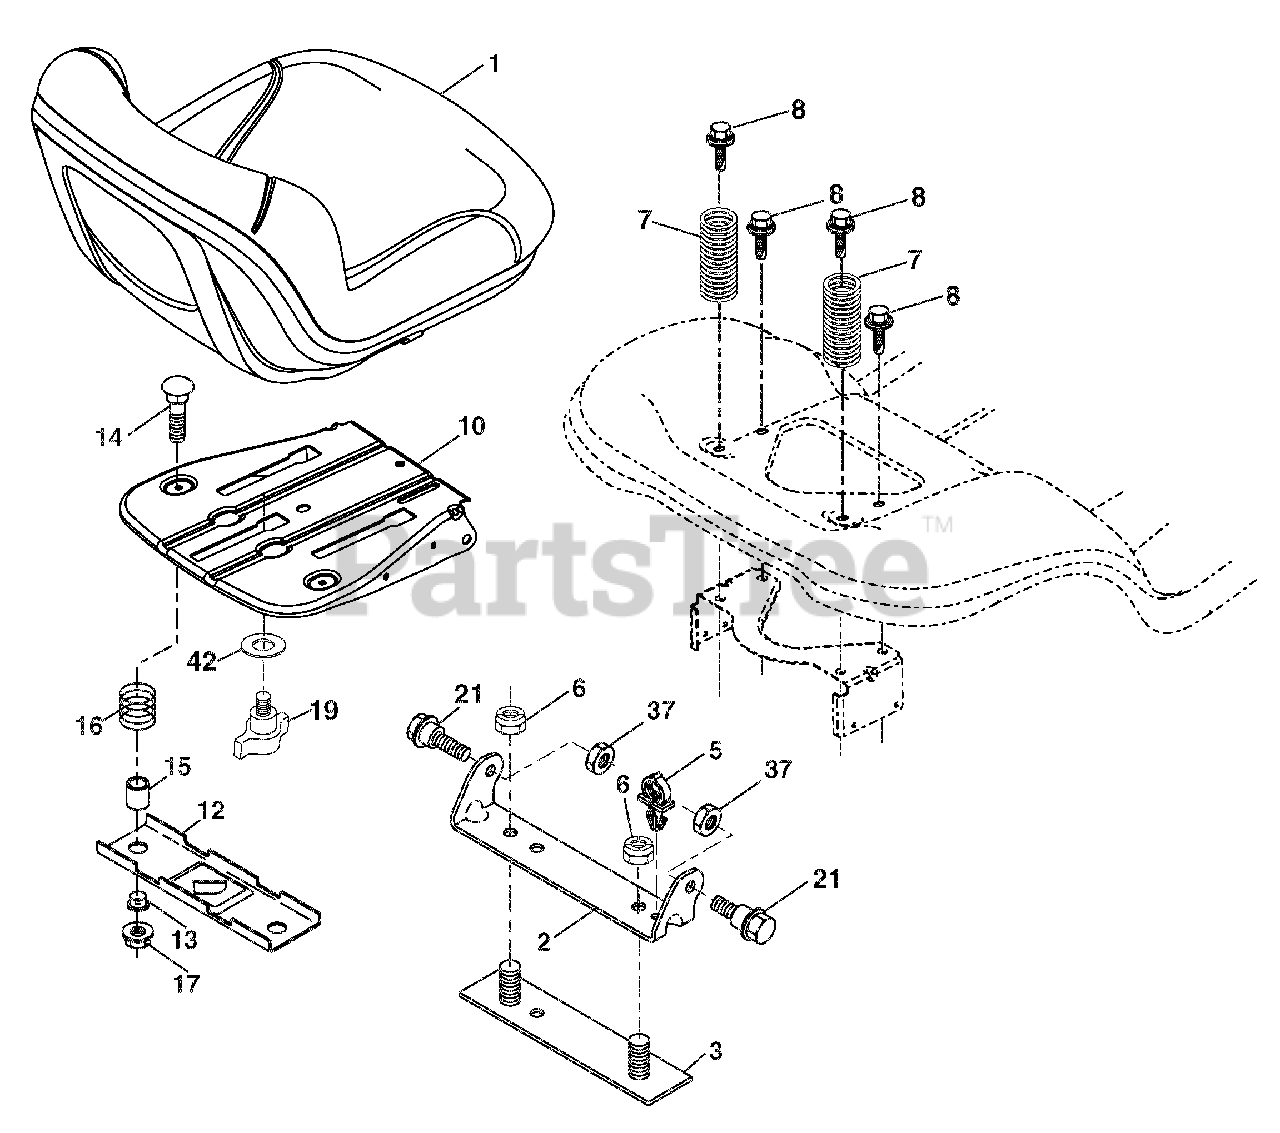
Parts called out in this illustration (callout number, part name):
1	SEAT.TA110.BLACK.ARIENS
2	BRACKET.PIVOT.FENDER.2002
3	STRAP ASM.FENDER.94
5	CLIP.PUSH-IN.HINGED
6	Locknut, Washer Insert 3/8-16
7	SPRING.SEAT.CPRSN.2.250.BLK.ZI
8	BOLT.5/16-18UNCX3/4 W/SEMS.BLK
10	PAN, SEAT
12	BRACKET.MNT.OPC.SW.SEAT.TEX LT
13	BUSHING.SNAP.BLK.NYL..50 ID.
14	BOLT.RDHD.SHT.NK.1/4-20X1-1/2
15	SPACER.SPLIT..28X.96.YEL.ZINC
16	SPRING.CPRSN.PLATE.SW.1.310.GA
17	NUT.LOCK.1/4 LGE.FLG.GR.5.ZINC
19	KNOB.SEAT ADJ.3/8-16"TEX
21	BOLT.SHLD.5/16-18 UNC-2A.BLK D
37	Locknut, Washer Insert 5/16-18
42	WASHER.CUP.SEAT.TEX LT
